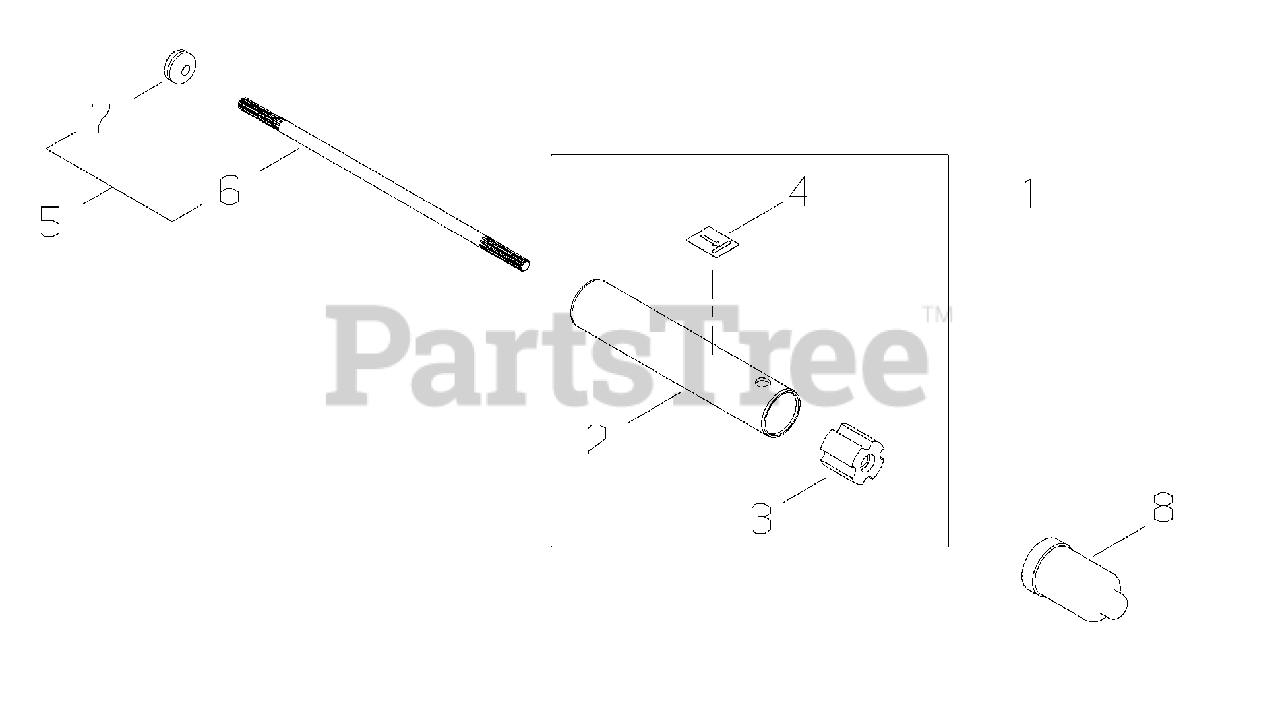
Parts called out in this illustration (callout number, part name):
1	MAIN PIPE ASSY
2	PIPE, MAIN
3	BUSHING
4	LABEL, INSTRUCTION
5	MAINSHAFT ASSY
6	MAINSHAFT
7	GROMMET
8	CAP
